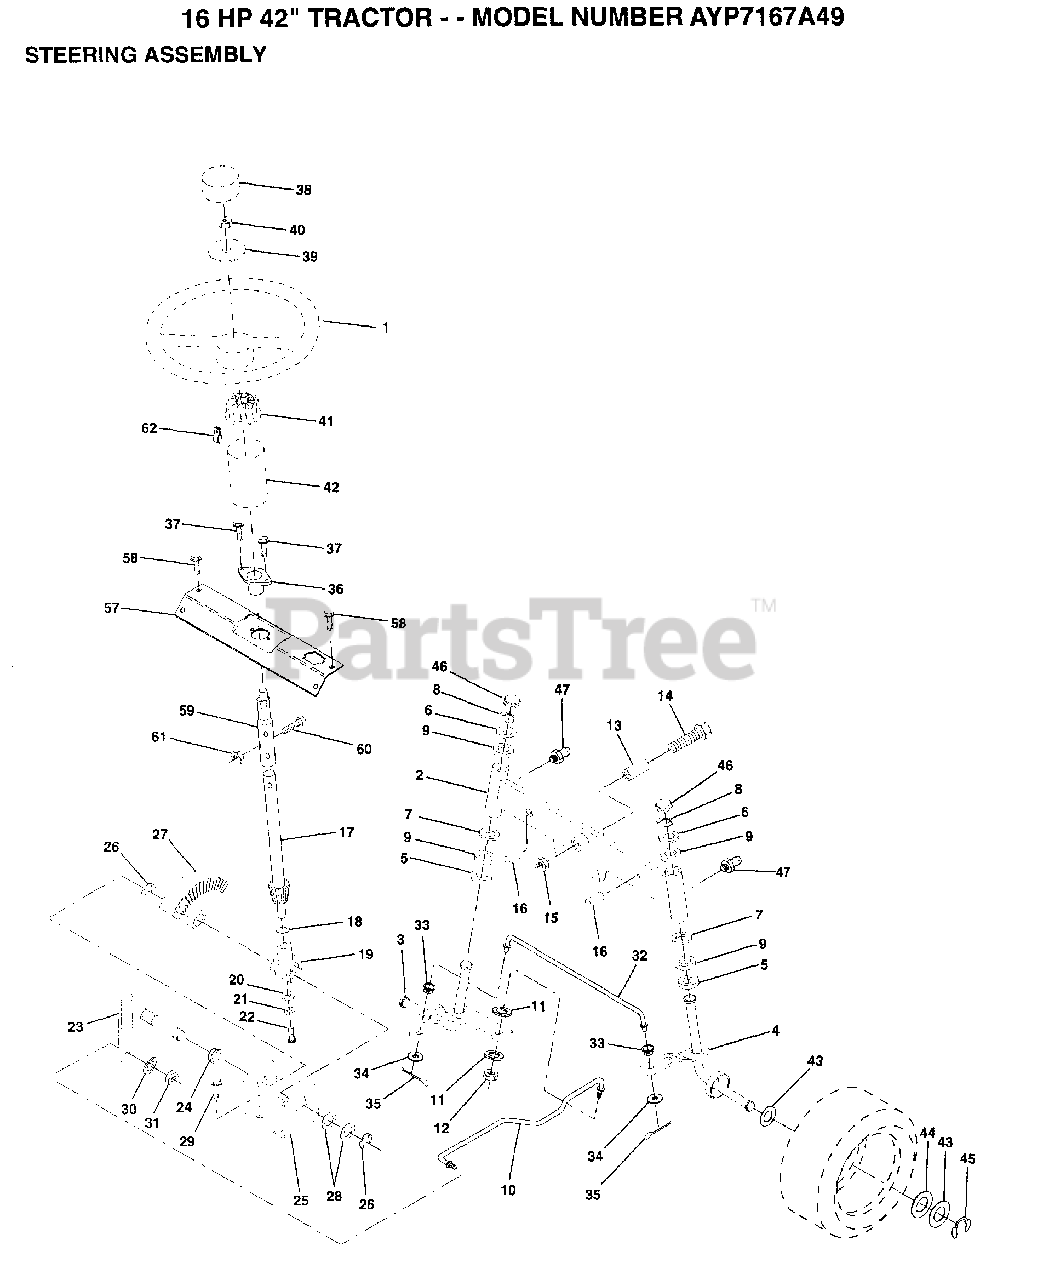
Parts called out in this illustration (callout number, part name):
1	WHEEL STR AYP BLK
2	AXLE ASM FRONT
3	SPINDLE LH
4	SPINDLE RH
5	WASHER .T
6	WASHER
7	WASHER
8	RING
9	COL. SRTG. BEAR.
11	LOCKWASHER
13	BEARING
14	BOLT HEX 5/8-11
15	"NUT-LOC,FLANGE LT"
16	AXLE PIN
17	SHAFT ASM STEERIN
18	THRUST WASHER
19	SUPPORT.SHAFT
21	LOCKWASHER
22	"SCREW,SPECIAL"
24	NYLINER T
25	"BRKT,STEERING"
26	RING
27	GEAR SECTOR
28	WASHER .T
29	SCREW
30	LOCKWASHER
32	TIE ROD
33	BUSHING.DRAGLINK
34	WASHER
35	COTTER PIN
38	CAP STEER AYP
39	WASHER T
40	GRIPCO NUT
41	ADAPTER-WHEEL LT
42	BOOT SHAFT STEER
43	WASHER
44	WASHER
45	RING
46	CAP
47	ZERK M
57	SUPPORT SHAFT STR
58	SCREW HEX CRT
59	SHAFT EXT STEER
60	BOLT
61	NUT
62	CLIP TIMMERMAN
